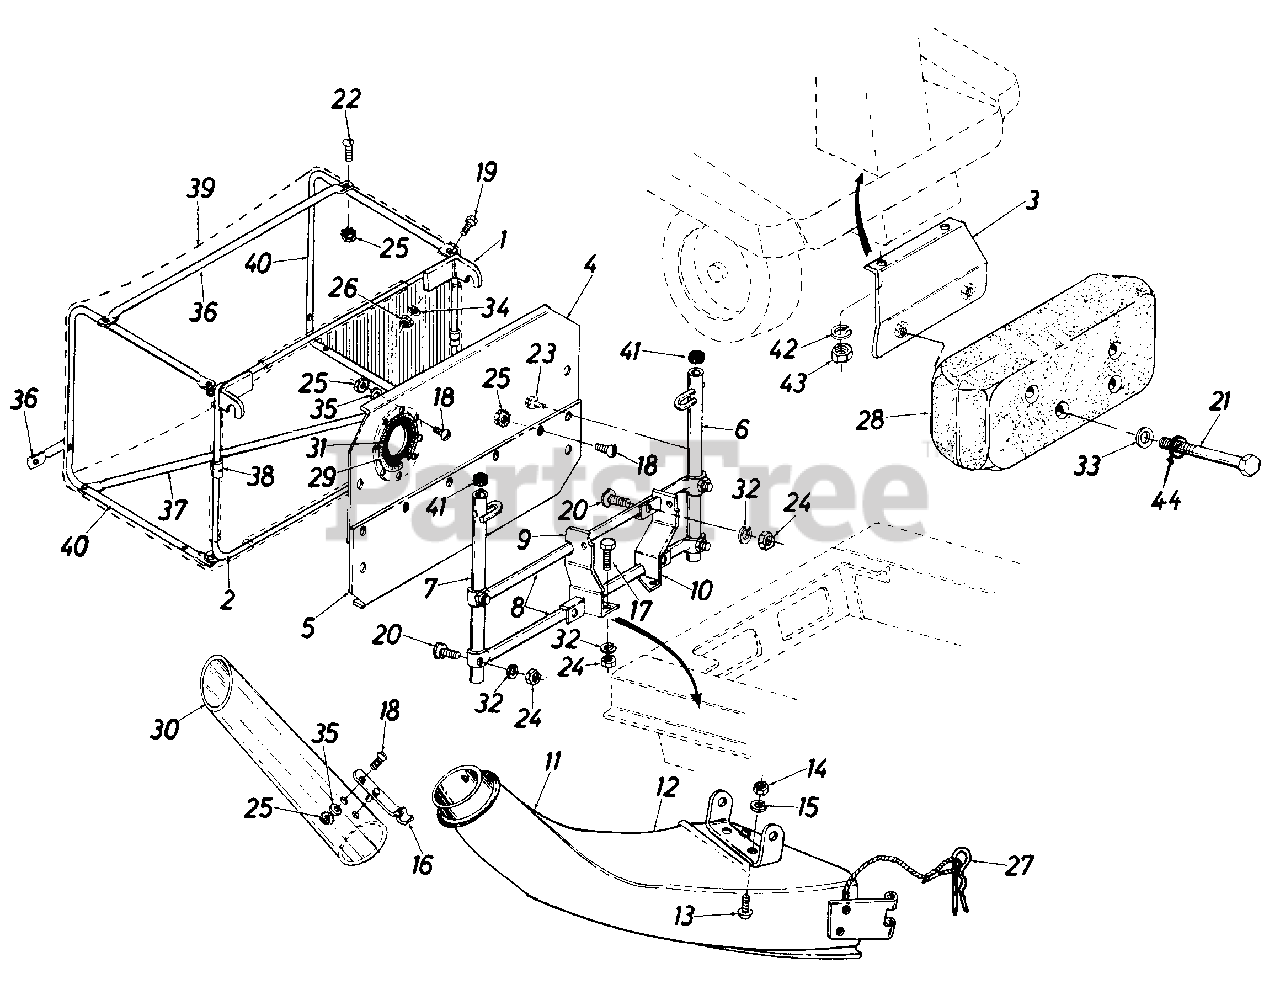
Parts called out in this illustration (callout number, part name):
1	Catcher Frame Ass'y. - Upper
2	Catcher Frame Ass'y. - Lower
3	Counterweight Support Bracket. Ass'y.
4	Front Cover- Upper Half
5	Front Cover- Lower Half
6	L.H. Vertical SupportAss'y.
7	R.H. Vertical Support Ass'y.
8	Horizontal Support Tubing
9	Catcher Support Brkt. Ass'y.-R.H.
10	Catcher Support Brkt. Ass'y.-L.H.
11	Discharge Chute Ass'y.
12	Brkt. Chute Hinge
13	Carr. Bolt 1/4-20 x .62" Lg.
14	Hex Nut 1/4-20 Thd.*
15	L-Wash. 1/4" I.D.*
16	Spring Lock Ass'y.
17	Hex Bolt 5/16-18 x .75" Lg.*
18	Truss Mach. Scr. #10-24 x .38" Lg.*
19	Hex Bolt 1/4-20 x .62" Lg.*
20	Curved Carf. Bolt 5/16-18 x 1.75" Lg.
21	Hex Bolt 3/8-16 x 4.50" Lg.*
22	Truss Mach. Scr. #10-24 x 1.0" Lg.*
23	Hex Wash. Hd. AB-Tap Scr. 1/4" x.62" Lg.
24	Hex Nut 5/16-18 Thd.*
25	Hex Sems Nut #10-24 Thd.
26	Hex Nut 1/4-2 Thd.*
27	Internal Cotter Pin
28	Counter Weight - 38#
29	Trim Strip - 24"
30	Grass Chute Tube
31	Rubber Flap
32	L-Wash. 5/16" I.D.*
33	Flat Washer 3/8" 1 .D. x 1.25" O.D. x .17
34	L-Wash. 1/4" I.D.*
35	Fl-Wash. .203" I.D. x.41" O.D. x .040
36	Grass Catcher Handle
37	Grass Catcher Handle
38	Tubing Connector 1/2" I.D.
39	Grass Bag
40	CatcherSide Frame
42	L-Wash. 5/16" I.D.*
43	Hex Nut 5/16-18 Thd.*
44	Bell-Wash. 3/8" I.D. x 7/8" O.D.
